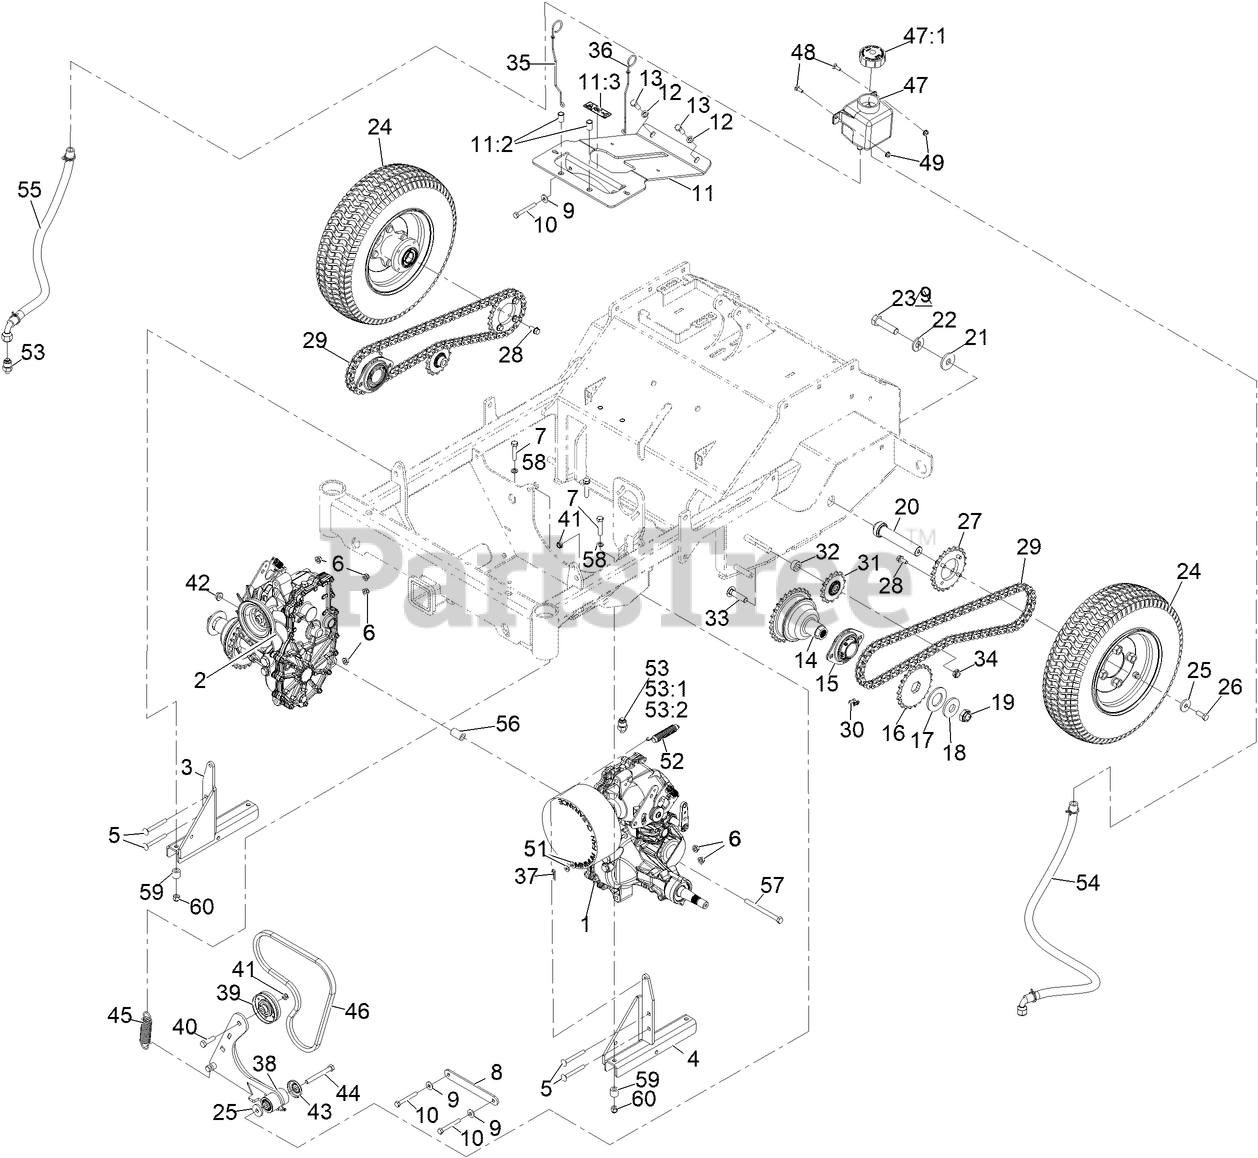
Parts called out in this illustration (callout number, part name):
1	HYDRO-ZT3100, LH
2	HYDRO-ZT3100, RH
3	MOUNT-HYDRO, RH
4	MOUNT-HYDRO, LH
5	SCREW-CARR
6	NUT-HF, NI
7	SCREW-HH
8	CROSSMEMBER-TRANSMISSION
9	WASHER-SPRING
10	SCREW-HH
11	SUPPORT-COVER
11:2	NUT-CLINCH
11:3	DECAL-DANGER
12	WASHER-LOCK
13	SCREW-HH
14	HUB-BELL
15	BEARING-FLANGED
16	SPROCKET
17	WASHER-SPACER
18	WASHER-BELLEVILLE
19	NUT-LOCK
20	AXLE-WHEEL, DRIVE
21	WASHER-SPACER
22	WASHER-BELLEVILLE
23	SCREW-HH
24	WHEEL AND TIRE ASM
25	WASHER-FLAT
26	SCREW-HH, LOCK
27	SPROCKET
28	SCREW-HHF
29	CHAIN-ROLLER
30	LINK-CONNECTING
31	SPROCKET-IDLER, 15T
32	SPACER
33	SCREW-CARR
34	NUT-HEX
35	ROD-BYPASS, LH
36	ROD-BYPASS, RH
38	IDLER ARM ASM
39	PULLEY-IDLER
40	SCREW-HH
42	NUT-HF, NI
43	GUARD-TOP
44	SCREW-HH
45	SPRING-EXTENSION
46	BELT-V, COGGED
47	TANK-HYD
47:1	CAP-RESERVOIR, HYD
48	BOLT-CARR
49	NUT-HF
51	WASHER
52	SPRING-EXTENSION
53	FITTING-STRAIGHT
53:1	O-RING
53:2	O-RING
54	HOSE ASM
55	HOSE ASM
56	SPACER
57	SCREW-HH
58	SPACER-BRAKE, PARKING
59	SPACER
60	NUT-LOCK
